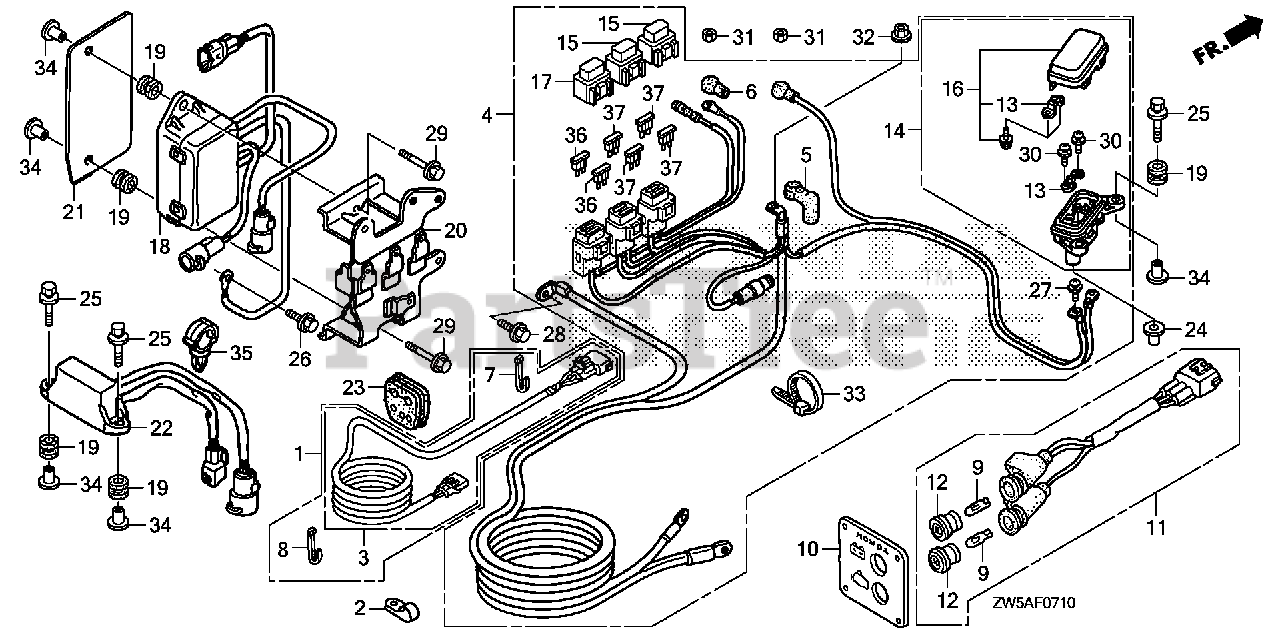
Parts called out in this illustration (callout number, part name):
1	CORD KIT, INDICATOR (3P/6P) (ANALOG)
2	CLAMP F, CABLE
3	WIRE ASSY., INDICATOR (3P/6P) (ANALOG)
4	CABLE ASSY., STARTER
5	COVER, STARTER TERMINAL
6	COVER A, MAGNETIC SWITCH
7	TIE, CABLE (2.4X92) (NATURAL)
8	TIE, CABLE (2.4X92) (NATURAL)
13	FUSE (90A)
14	BOX ASSY., FUSE (90A)
15	COVER ASSY., FUSE (30A)
16	COVER ASSY., FUSE (90A)
17	COVER ASSY., FUSE (10A)
18	RELAY ASSY., POWER TILT
19	GROMMET, RELAY
20	BRACKET, RELAY
21	INSULATOR, RELAY
22	RELAY ASSY., MAIN
23	GROMMET, CASE (LOWER) (A)
24	GROMMET A, LEG SHIELD
25	BOLT-WASHER (6X27) (CT200)
26	BOLT, FLANGE (6X12) (CT200)
27	BOLT-WASHER (5X9)
28	BOLT, FLANGE (8X18)
29	BOLT, FLANGE (6X25)
30	SCREW-WASHER (5X10)
31	NUT, HEX. (6MM)
32	NUT-WASHER (8MM)
33	BAND, WIRE HARNESS
34	COLLAR, MODULE IGNITION CONTROL CASE (CDI)
35	CLIP, WIRE HARNESS (BLACK)
36	FUSE, BLADE (10A)
37	FUSE, BLADE (30A)
